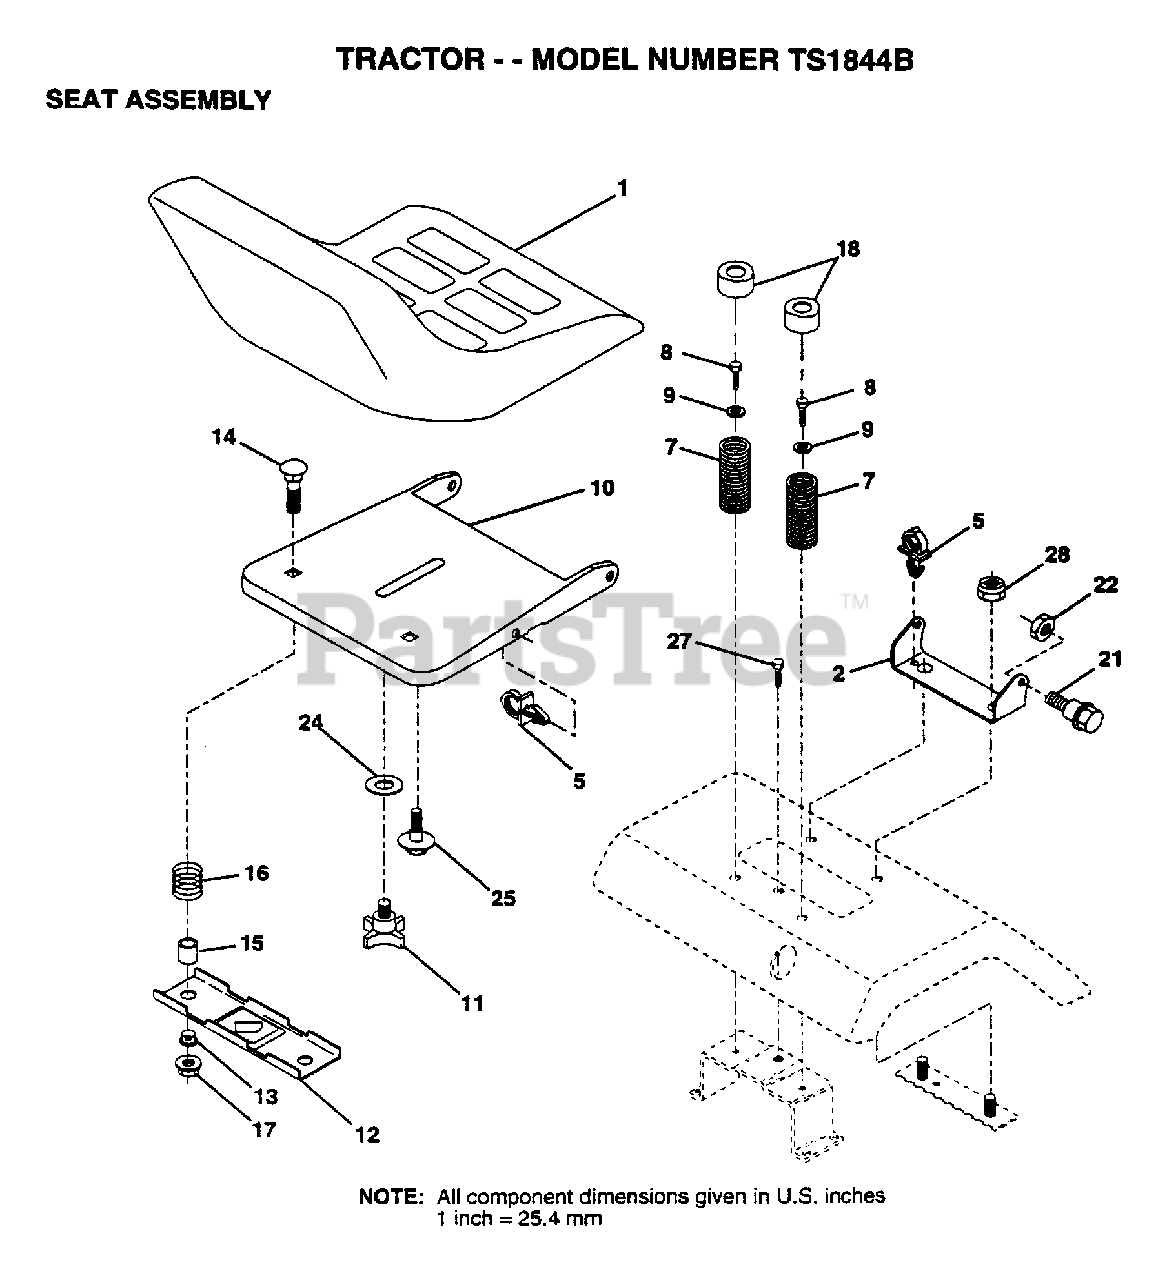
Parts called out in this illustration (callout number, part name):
2	BRACKET PVT SEAT
5	CLIP.PUSH-IN.HING
7	SPRING COMPRESSIO
8	SCREW LT
9	WASHER
11	"KNOB 1/2"" YT"
12	BRKT SWITCH
13	BUSHING
15	SPACER SPLIT
16	SPRING COMPRESSED
18	CAP SPRING
21	BOLT.SHLD.5/16-18
24	WASHER
25	"BOLT,SHOULDER"
27	SCREW LT
